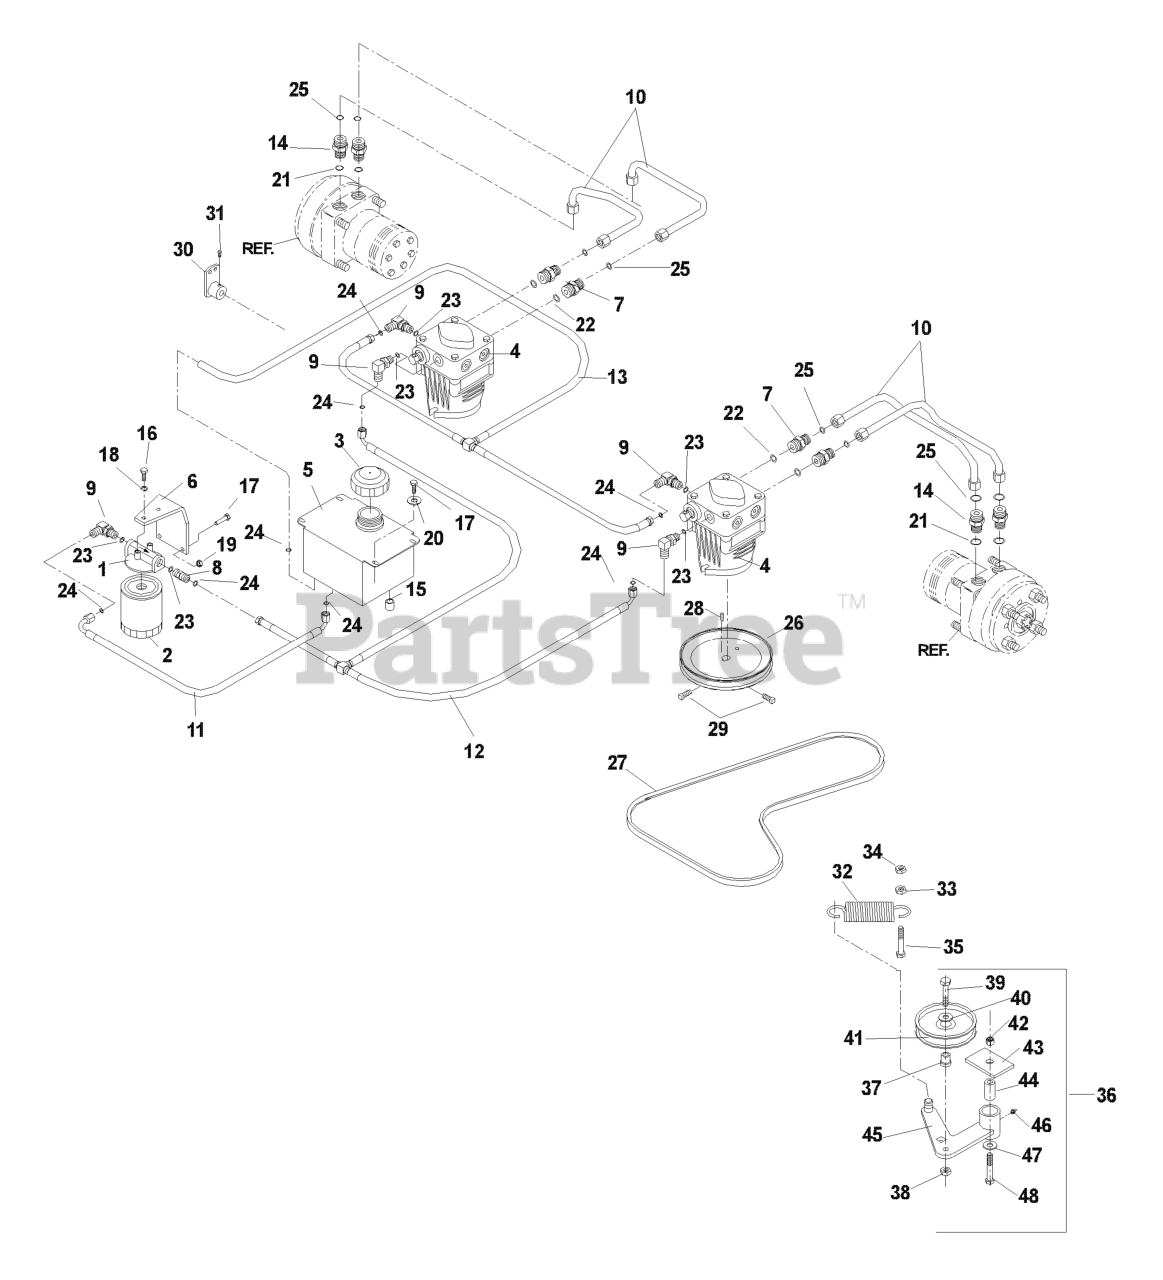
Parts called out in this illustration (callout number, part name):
1	FILTER HEAD
2	HYDRAULIC OIL FILTER
3	HYDRAULIC CAP
4	HG_PUMP
6	OIL FILTER BRKT
7	FITTING, STRAIGHT F6400-8-8-0
8	STRAIGHT FITG
9	ELBOW, F6801-6-6-0 90 DEGREE
10	HYDRAULIC HOSE
12	TEE ASSEMBLY
13	TEE ASSEMBLY
15	NUT 9/16-18 JIC CAP
16	HCS 1/4C X 5/8
17	HCS 1/4C X 3/4 HCS
18	LOCKWASHER 1/4"
19	NUT.1/4-20.HEX.NYLOC.ZD
20	WASHER 1/4 FLAT
27	PUMP BELT
28	KEY 5 MM SQ X 25 MM
29	SCREW 5/16C X 5/8 SQ HEAD
30	PUMP LEVER
31	5/16C X 5/8 "V" POINT
33	NUT 3/8C WHIZ
34	NUT 3/8-16 NYLOC
35	HCS 3/8C X 2
36	TORSION SPRING
37	BUSHING, IDLER FLANGE
38	NUT 3/8C CENTERBLOCK
39	HCS 3/8-16 X 1 3/4 GR5
40	WASHER 3/8 FLAT
41	IDLER PULLEY
42	NUT 1/2-13 HEX NYLOC ZD
44	PIVOT BUSHING
45	IDLER ARM WLDT
46	ZERK
47	WASHER 1/2 FLAT
48	HCS 1/2C X 3 1/4
